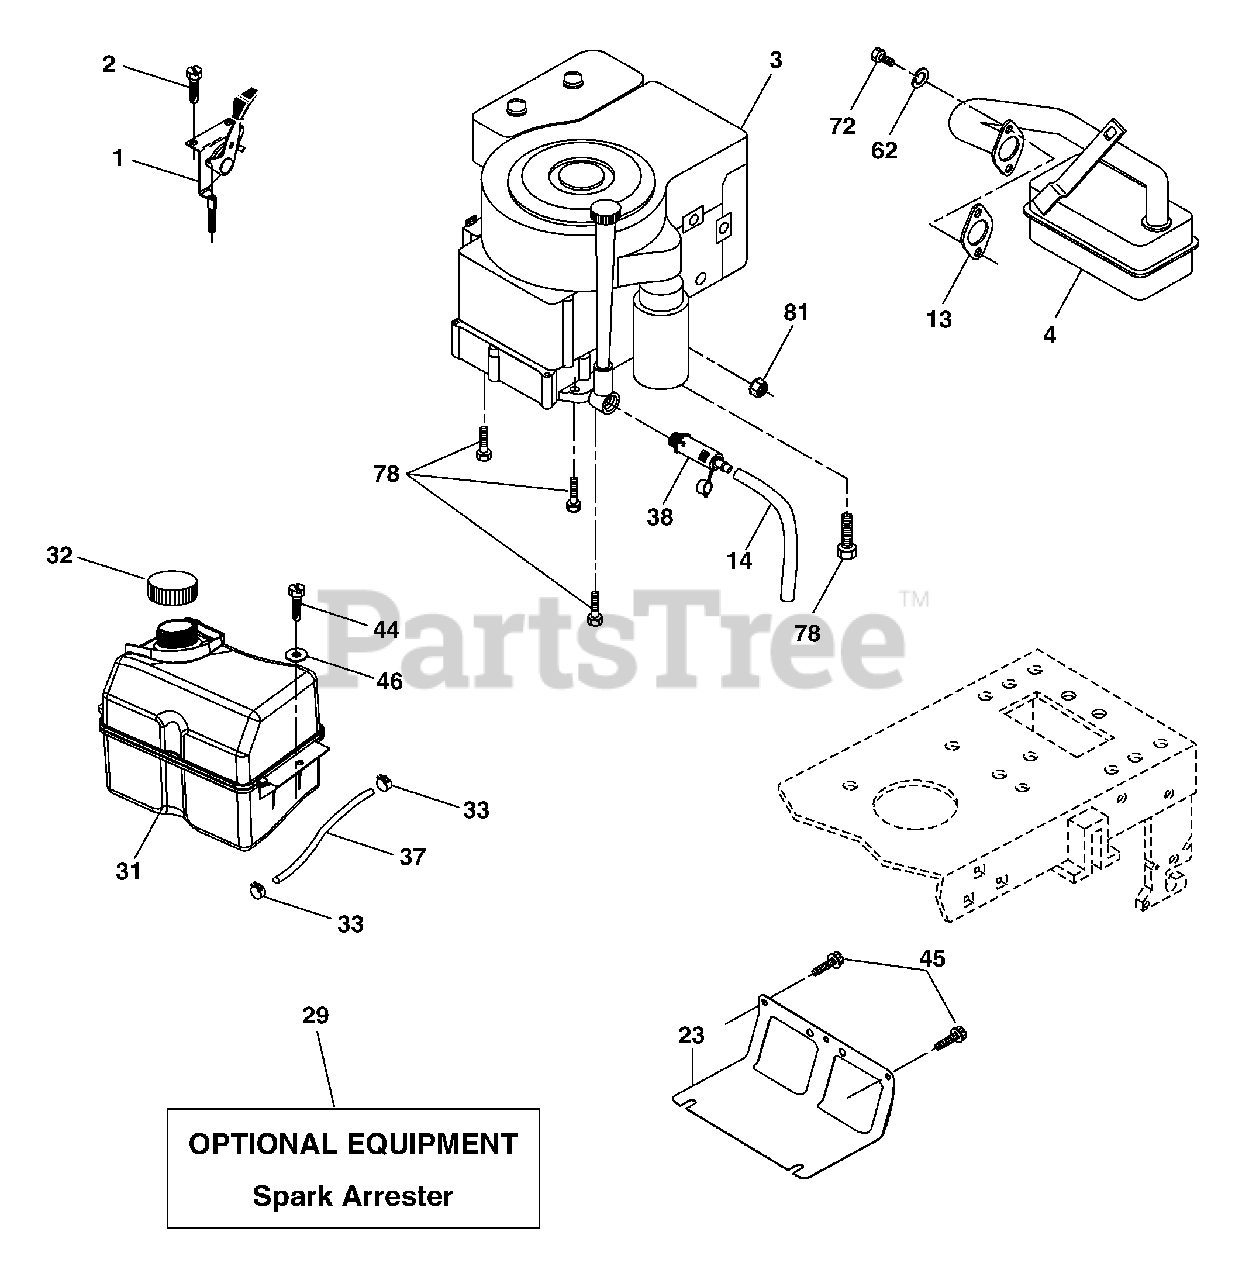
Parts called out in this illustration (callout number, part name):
1	Control, Throttle
2	Screw Hex Thd Cut 1/4-20 x 1/2
4	Muffler
13	Muffler Gasket
14	Tube Oil Drain
23	Shield, Browning/Debris Guard
29	Arrester, Spark
31	Tank, Fuel
32	Cap, Fuel
33	Clamp, Hose Blk
37	Line, Fuel
38	Plug Drain Oil Easy
44	Screw Hex Wsh Thdrol 1/4-20 x 3/4
45	Screw Hex Wsh Thdrol 3/8-16 x 3/4
46	Washer 9/32 x 7/8 x 16 Ga.
62	Washer Split
72	Screw Socket Hd 5/16-18 x .75
78	Screw 3/8-16 x 1-1/4
81	Nut Keps Hex 1/4-20 unc
